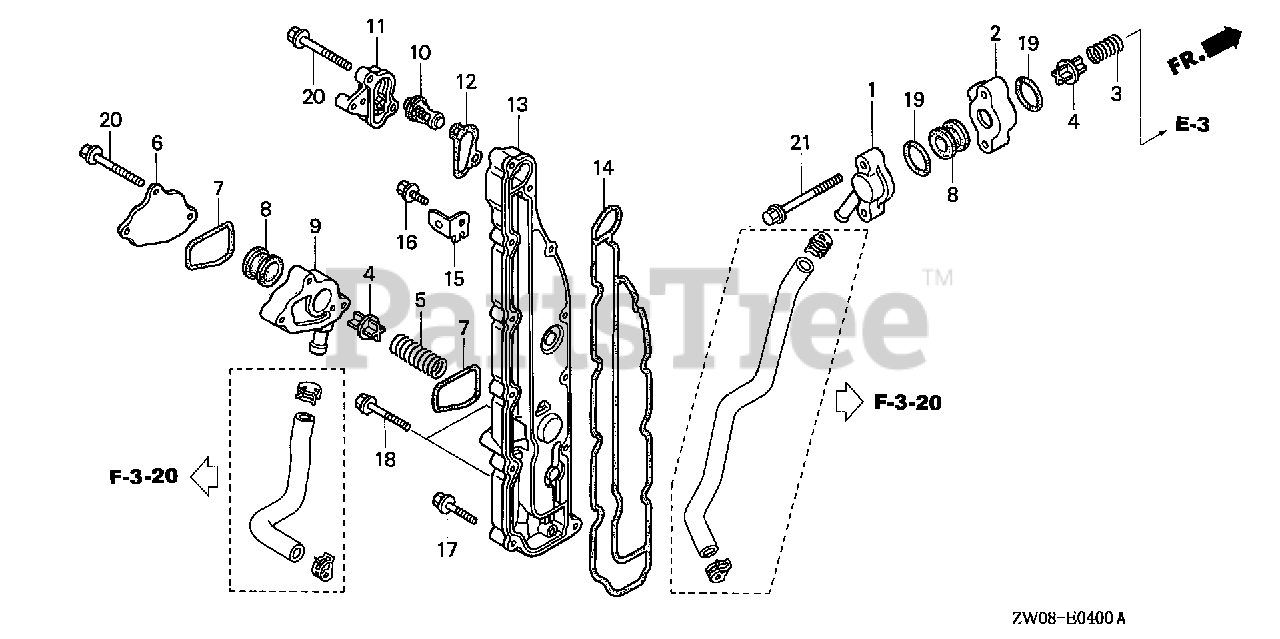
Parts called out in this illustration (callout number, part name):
1	COVER, FLUSH VALVE
2	SPACER, FLUSH VALVE *NH8* (DARK GRAY)
3	SPRING, FLUSH VALVE
4	VALVE, RELIEF
5	SPRING, RELIEF VALVE
6	COVER, RELIEF VALVE
7	GASKET, RELIEF VALVE COVER
8	GASKET, RELIEF VALVE
9	SPACER, RELIEF VALVE *NH8* (DARK GRAY)
10	THERMOSTAT ASSY. (72 DEGREES C)
11	COVER, THERMOSTAT
12	GASKET, THERMOSTAT COVER
13	COVER, WATER JACKET *NH8* (DARK GRAY)
14	GASKET, WATER JACKET COVER
15	STAY A, IGNITION WIRE CLAMP
16	BOLT, FLANGE (6X12) (CT200)
17	BOLT, FLANGE (6X25)
18	BOLT, FLANGE (6X32) (CT200)
19	O-RING (31.5X2.4) (ARAI)
20	BOLT, FLANGE (6X40)
21	BOLT, FLANGE (6X55)
